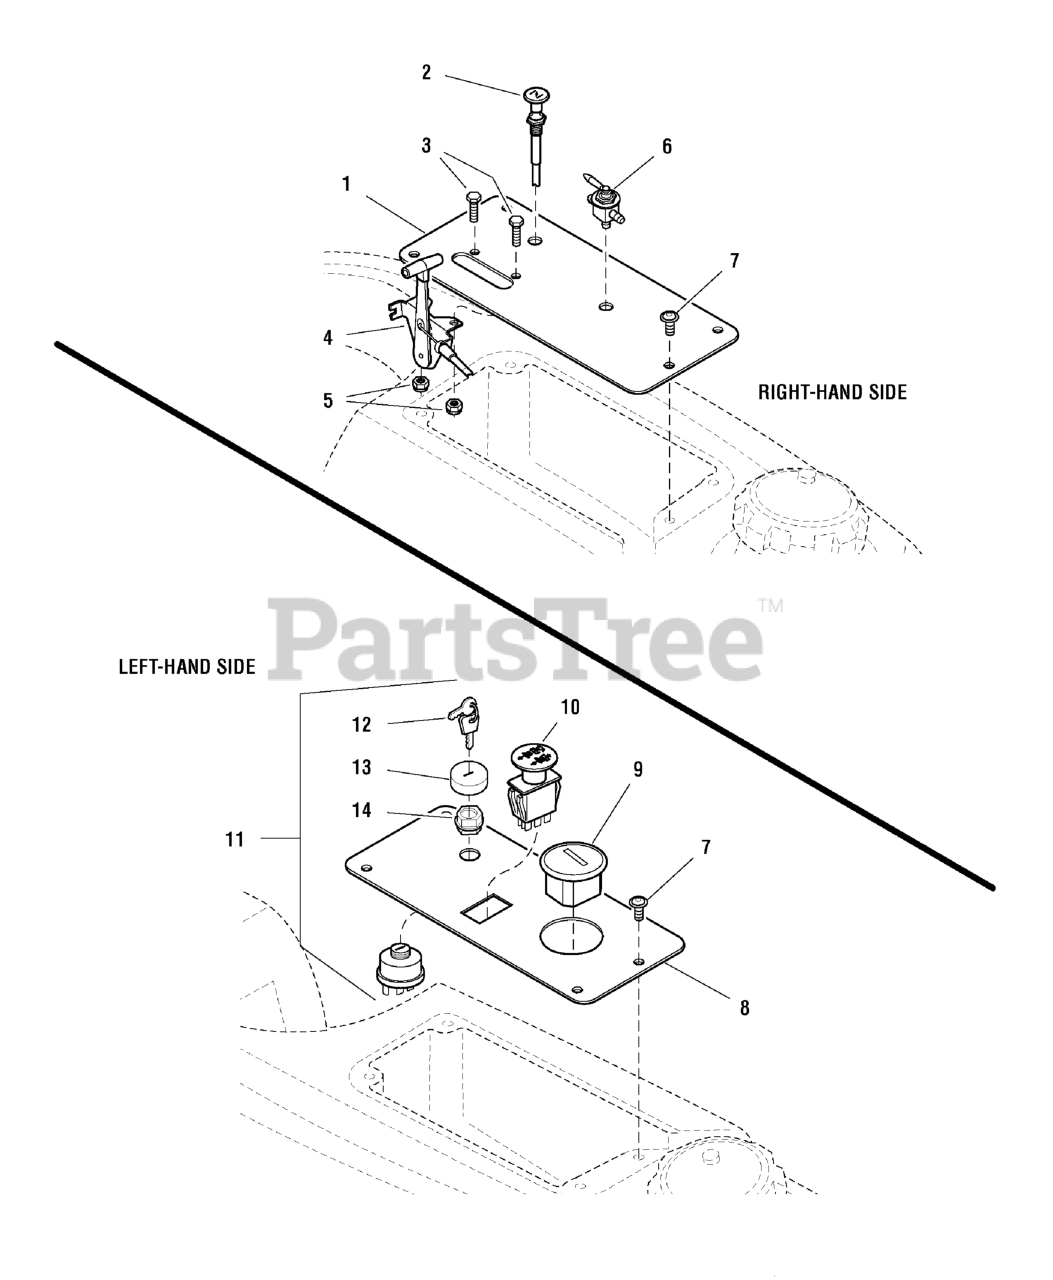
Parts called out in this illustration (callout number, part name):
1	PANEL, Control - RH
2	CABLE, Choke Control
3	BOLT, 1/4-20 x 3/4
4	CABLE, Throttle, 38"
5	NUT, 1/4-20 HEX SERR. FLANGE
6	VALVE, Fuel Shut Off
7	SCREW, Allen Head, 1/4-20 x 1/2
8	PANEL, Control-LH
9	HOUR METER
10	SWITCH, BLADE ENGAGEMENT
11	SWITCH, IGNITION, 6 POST
12	KEY, IGNITION MOLDED SET
13	COVER, PLASTIC, SNAP ON
14	PLASTIC NUT
